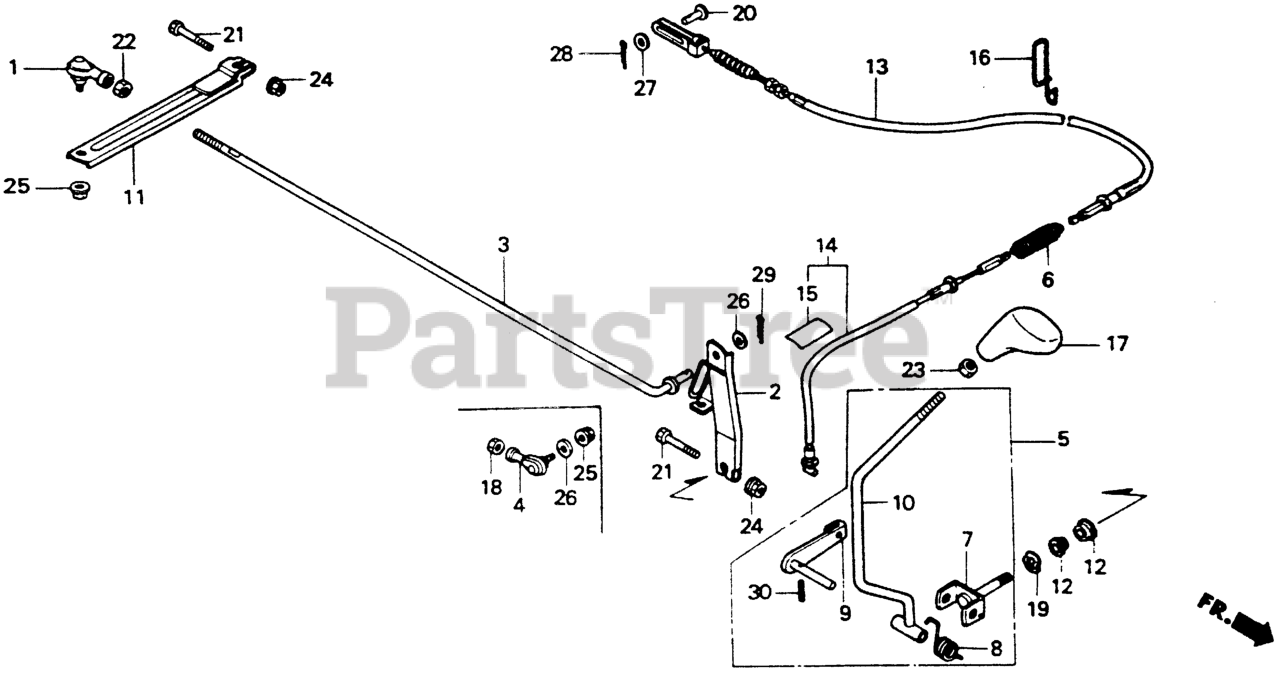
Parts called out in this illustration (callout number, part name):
1	JOINT, R. BALL
2	ARM, CHANGE
3	ROD, GEARSHIFT
3	ROD, GEARSHIFT (NOT AVAILABLE)
5	SHAFT, CHANGE LEVER
6	SPRING, CLUTCH DAMPER
7	SHAFT, CHANGE LEVER
8	SPRING, CHANGE LEVER
9	LINK, CLUTCH
10	LEVER, CHANGE (NOT AVAILABLE)
11	ARM, TRANSMISSION CHANGE
12	BUSH (15X19X18)
13	CABLE C, CLUTCH (CHANGE) (NOT AVAILABLE)
14	CABLE D, CLUTCH (CHANGE) (NOT AVAILABLE)
15	TAPE, PROTECTOR
16	GUIDE, CLUTCH CABLE
17	KNOB, SHIFT LEVER *NH105* (MAT BLACK)
19	WASHER, WAVE (15MM)
20	PIN, CLUTCH JOINT
21	BOLT, HEX. (6X32)
22	NUT, HEX. (8MM)
23	NUT, HEX. (12MM)
24	NUT, FLANGE (6MM)
25	NUT, FLANGE (8MM)
26	WASHER, PLAIN (8MM)
27	WASHER, PLAIN (6MM)
28	PIN, COTTER (1.6X12)
29	PIN, COTTER (2.0X15)
30	PIN, SPRING (5X25)
